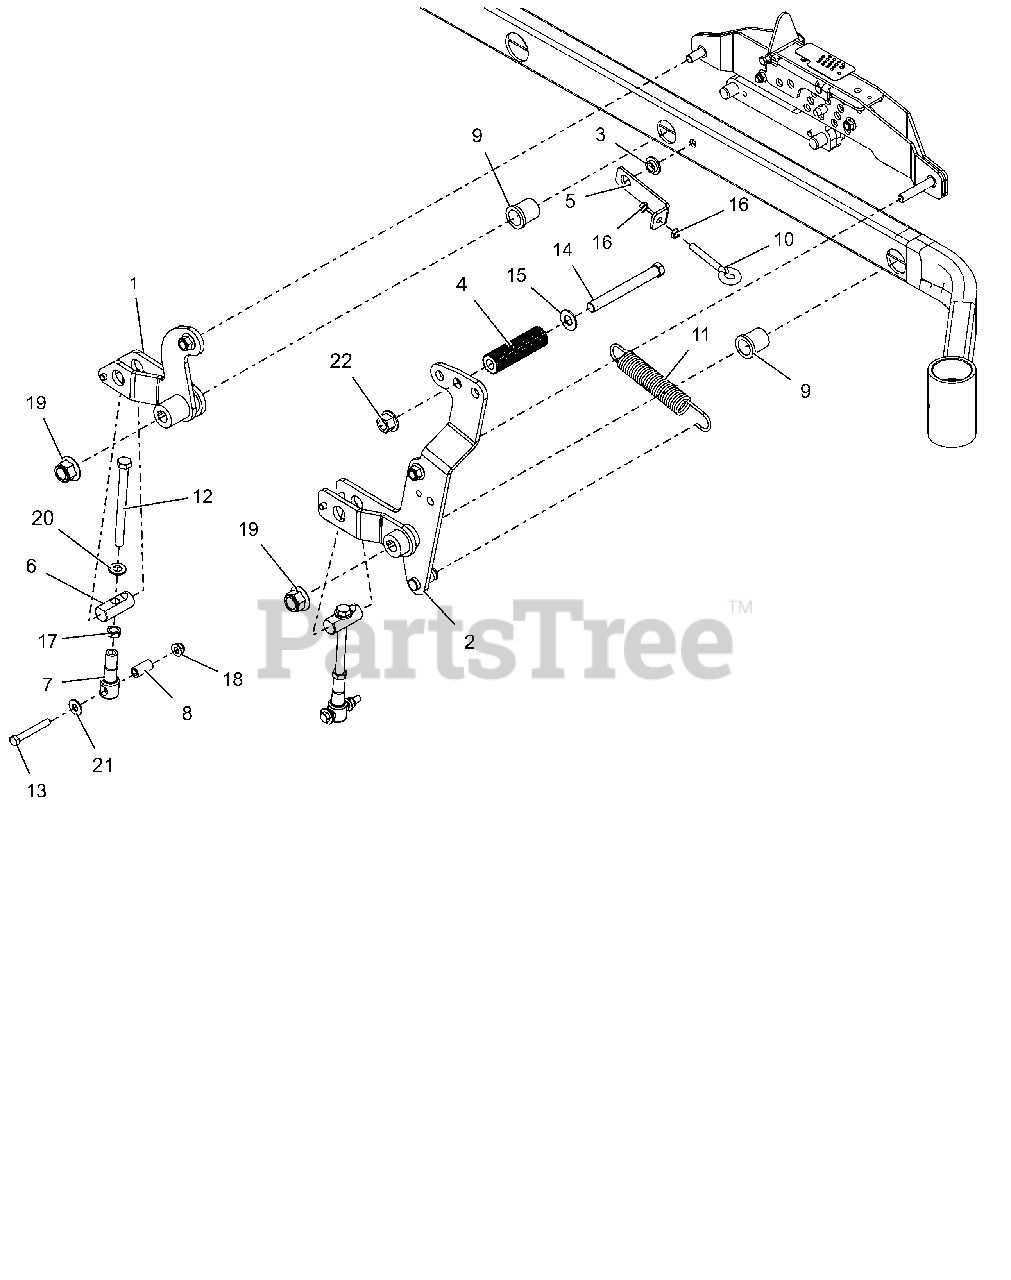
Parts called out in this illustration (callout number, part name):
1	REAR RH DECK LIFT ARM WMT- LF
2	FRT RH DECK LIFT ARM WMT- LF
3	BSHG-FLG .515X.750X.310X1.120
4	ROD, FOOT PEDAL (BLACK)
5	SPRING ANCHOR BRACKET - RED
6	PIN, DECK LIFT
7	LINK, DECK LIFT FORMED
8	SPACER, DECK LEVELING
9	BSHG-FLG 1.00X1.25X1.50X1.50
10	BLT-EYE .375-16X2.50 YWZC
11	SG-TENS .162X1.25X8.25 WLD 25
12	BOLT,.50-13X6.00-2.50 LG THD
13	BLT-HEX .38-16X2.75 GR8 YWZC
14	BLT, HEX .62-11X5.50 G5 FBP
15	WSHRFLT 5/8SAE CARBHARD FBP
16	NUT-HEX-JAM .375-16 YWZC
17	NUT-JAM .50-13 YWZC
18	@NUT-LK-NYL-FLG .38-16 YWZC
19	@NUT-LK-NYL-FLG .75-10 YWZC
20	FLATWASHER 1/2 SAE HARD 15906
21	@WSHR-FL-STL.438X1.00X.083 YWZ
22	NUT,FLG-TOP LK .625-11 FBP
